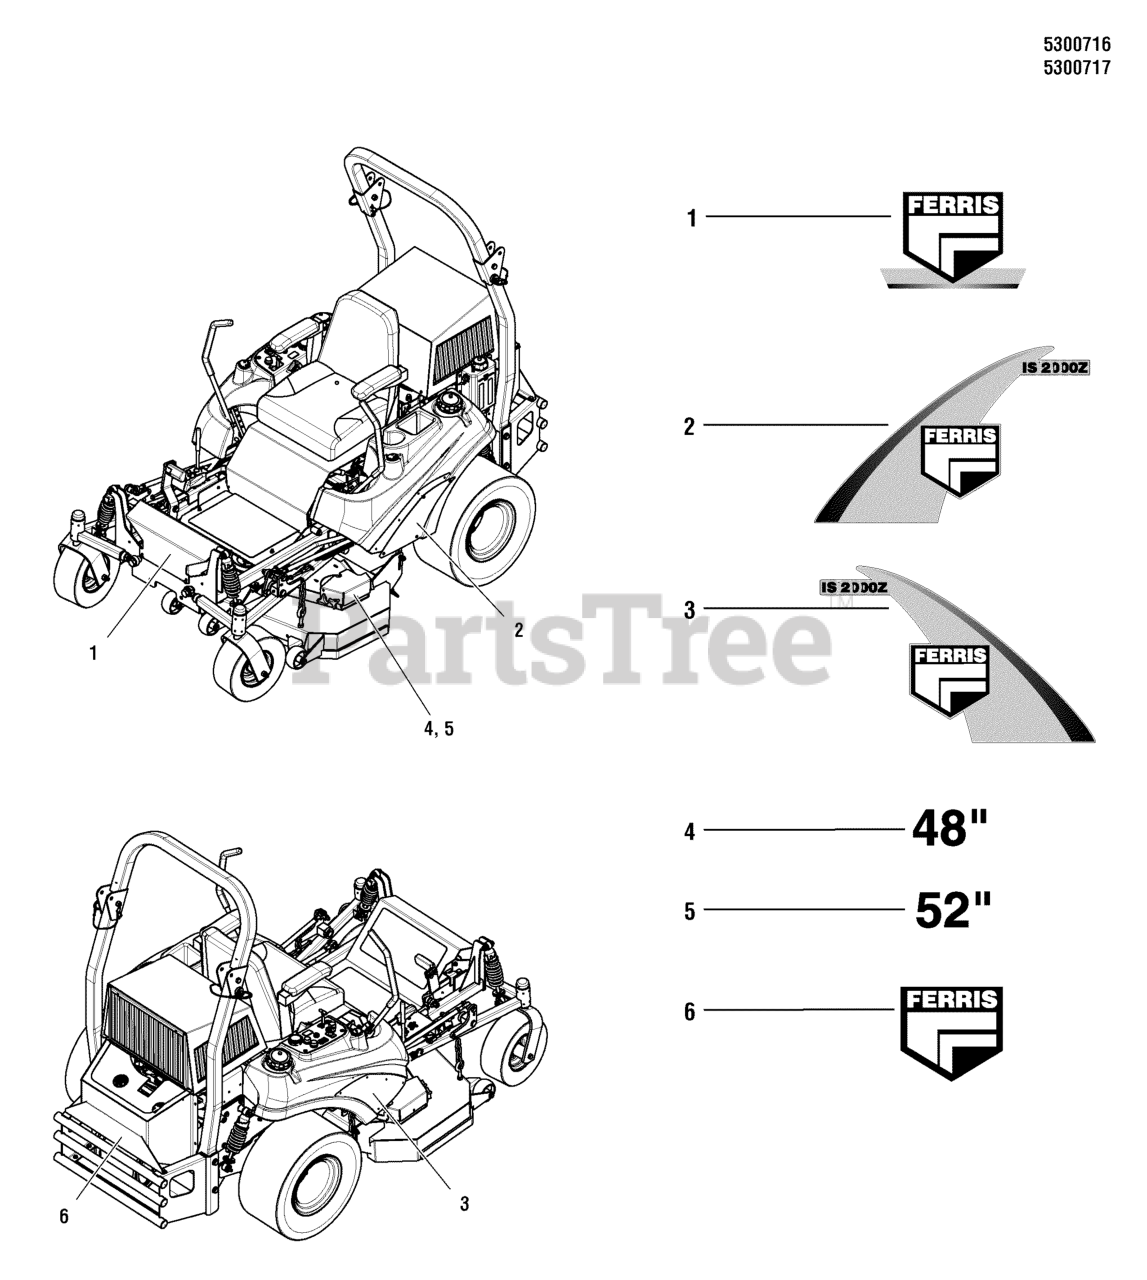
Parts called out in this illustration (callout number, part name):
2	DECAL, BADGE, IS2000Z, LH
3	DECAL, BADGE, IS2000Z, RH
4	DECAL, 48
5	DECAL, 52
